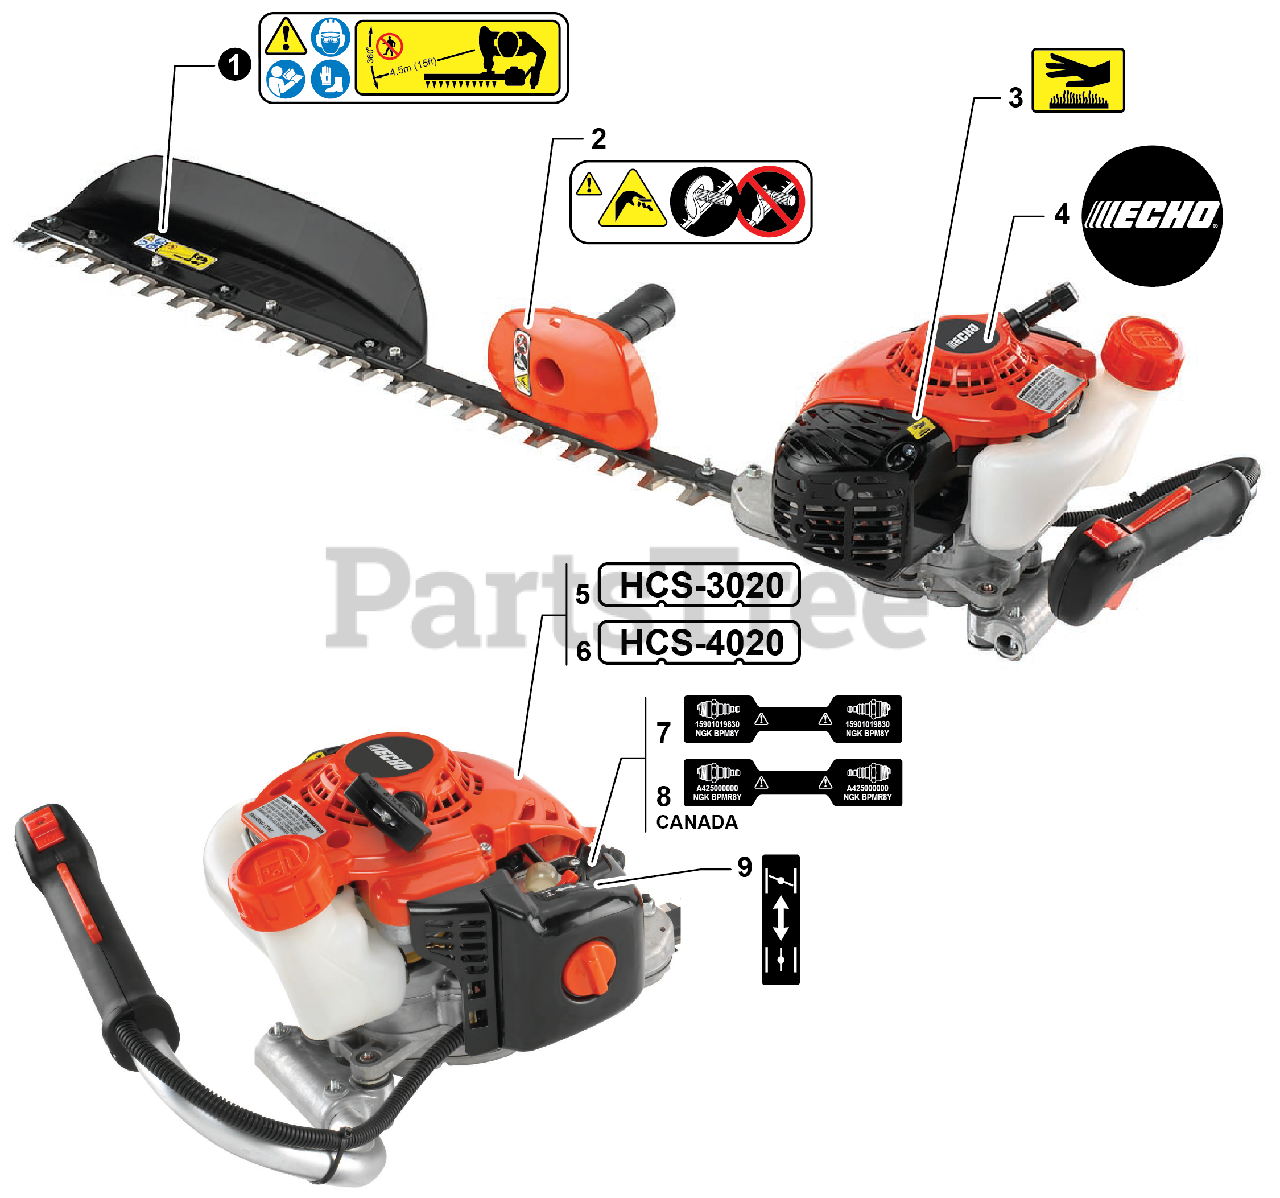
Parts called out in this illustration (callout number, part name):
1	LABEL, CAUTION
2	LABEL, CAUTION - ISO
3	LABEL, CAUTION - HOT
4	LABEL, RECOIL STARTER
5	LABEL, MODEL - HCS-3020
6	LABEL, MODEL - HCS-4020
7	LABEL, SPARK PLUG - BPM8Y
8	LABEL, SPARK PLUG - BPMR8Y
9	LABEL, CHOKE
